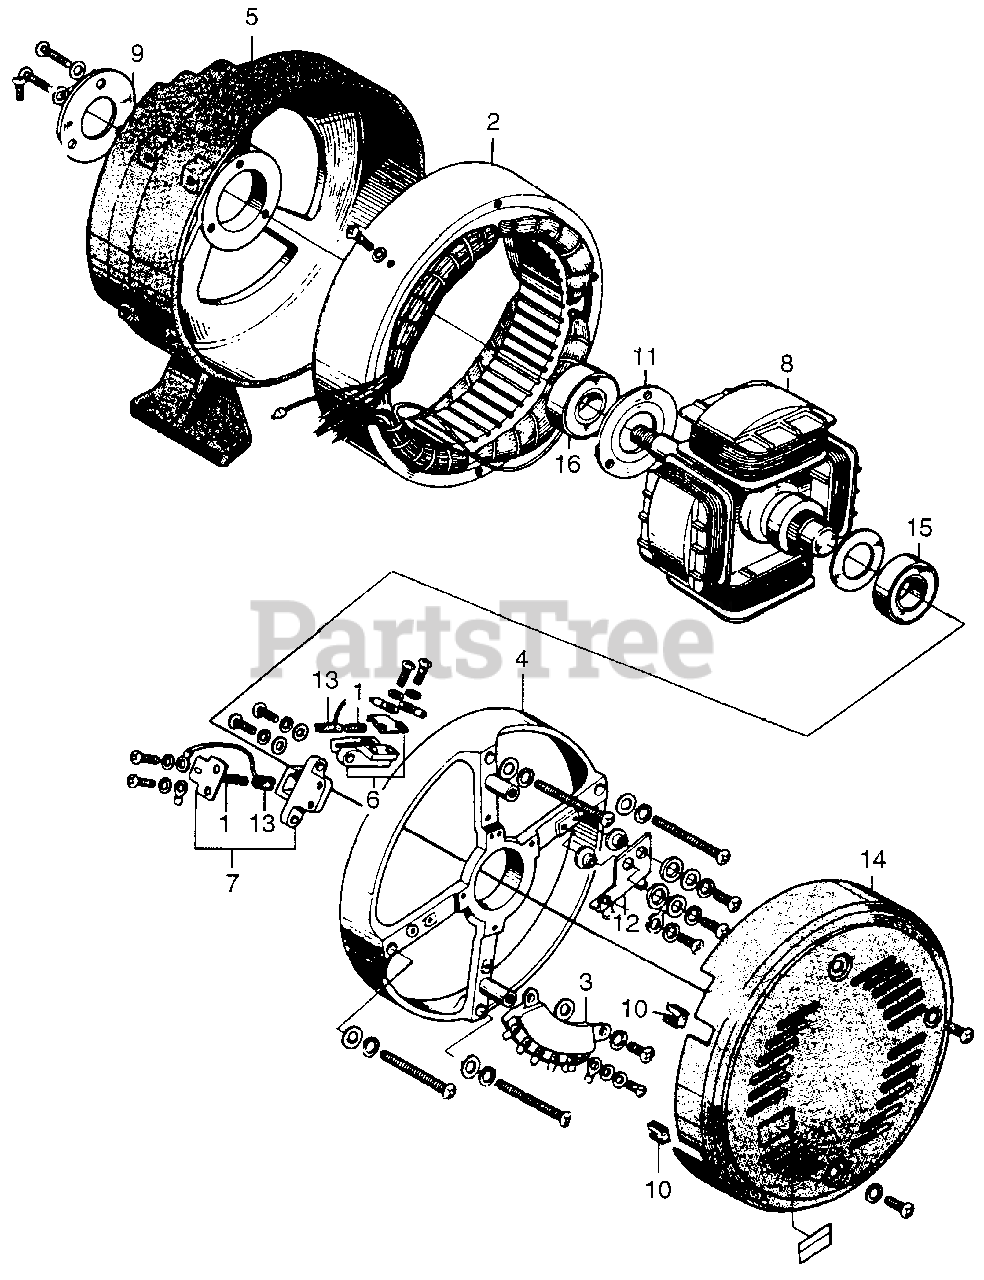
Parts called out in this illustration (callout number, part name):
1	SPRING, BRUSH (NOT AVAILABLE)
2	STATOR ASSY.
3	STACK ASSY. (NOT AVAILABLE)
4	COVER, END
5	COVER, FR. *R2* (SCARLET)
6	HOLDER B ASSY., BRUSH (NOT AVAILABLE)
7	HOLDER A ASSY., BRUSH (NOT AVAILABLE)
8	ROTOR ASSY.
9	BEARING, SIDE B
10	BUSHING, RUBBER
11	BEARING, SIDE A
12	DIODE ASSY., D.C.
13	BRUSH (NOT AVAILABLE)
14	COVER, CLEANER *PB6M* (CRYSTAL BLUE METALLIC)
14	COVER, CLEANER *NH31* (MCKINLEY WHITE) (NOT AVAILABLE)
15	BEARING, RADIAL BALL (6202UU)
16	BEARING, RADIAL BALL (6203UU)
NI	ALTERNATOR ASSY.
NI	WIRE HARNESS ASSY.
